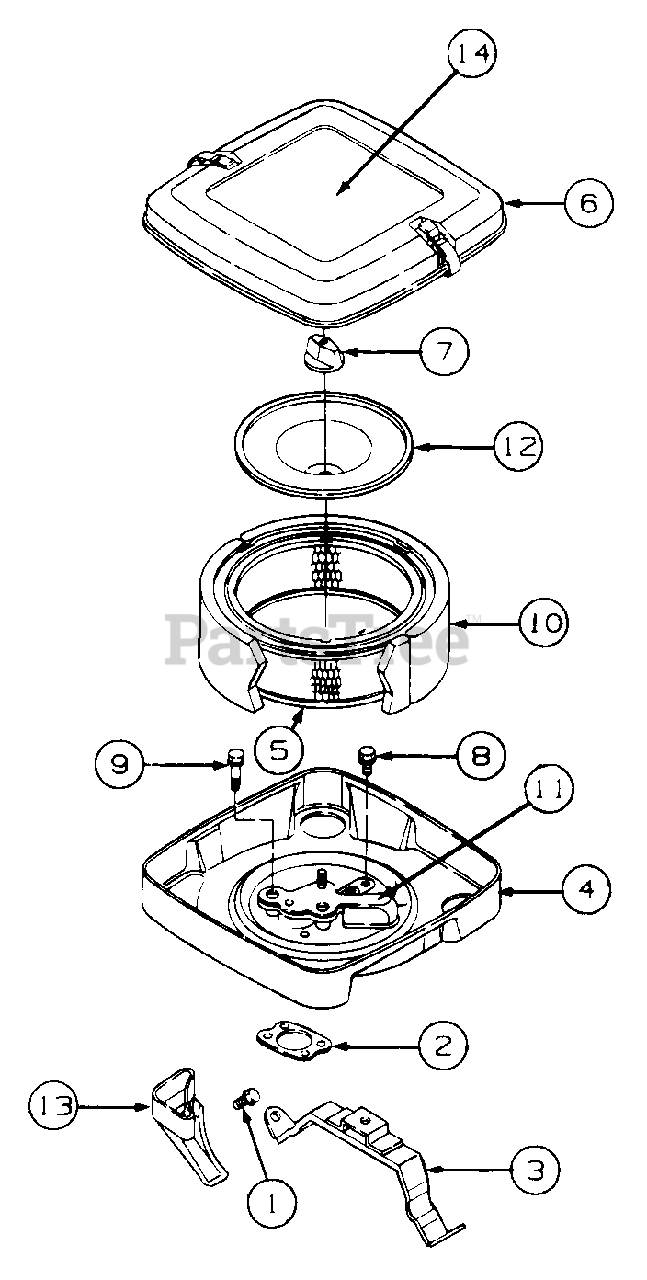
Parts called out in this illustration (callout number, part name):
1	Screw, Sems
2	Gasket, Air Cleaner
3	Bracket, Air Cleaner
4	Base, Air Cleaner
5	Cartridge, Air Cleaner
6	Cover, Air Cleaner
7	Knob, Air Cleaner
8	Screw, Sems
9	Screw, Sems
10	Element, Foam
11	Shield Assembly
12	Plate, Air Cleaner
13	Tube, Air Inlet
14	Label, V-Twin Engine
